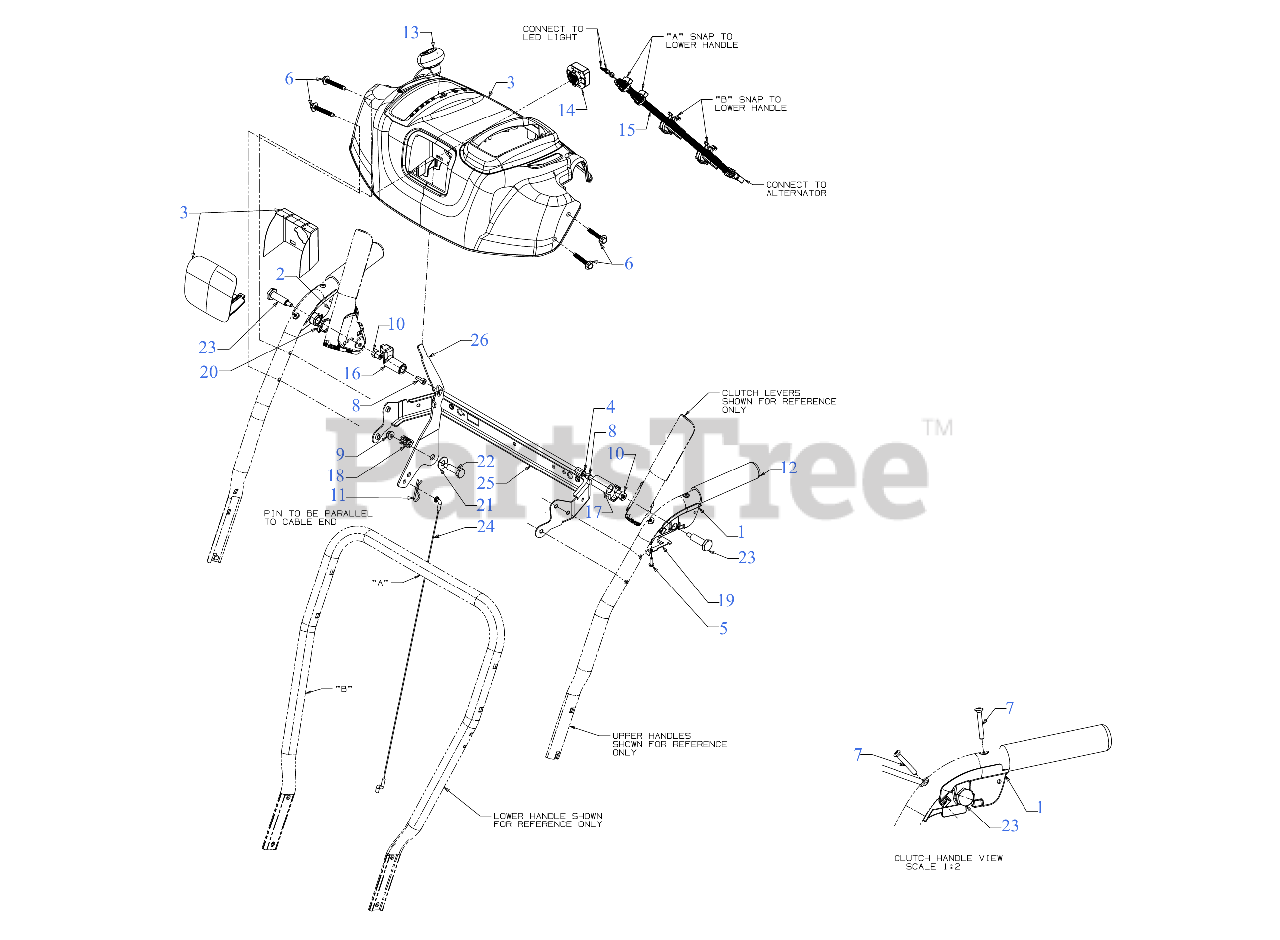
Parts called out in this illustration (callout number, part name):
1	CLUTCH LOCK HANDLE ASSEMBLY (LH)
2	CLUTCH LOCK HANDLE ASSEMBLY (RH)
3	HANDLE PANEL ASSEMBLY
4	PIVOT ROD
5	SCREW #8-16 x .50
6	SCREW 1/4-20 x 1.625
7	SCREW #10-24 x 1.375
8	SCREW 1/4-20 x .50
9	FLANGE LOCK NUT
10	HEX NUT W/PATCH
11	INTERNAL COTTER PIN
13	SHIFT KNOB
14	LED HEADLIGHT SOCKET (150 LUMNES)
15	LIGHT HARNESS
16	LOCK PLATE
17	CLUTCH LOCK CAM
18	COMPRESSION SPRING
19	CLUTCH SPRING
20	TORSION SPRING
21	FLAT WASHER .40X.88X.060
22	SHOULDER SCREW
23	SHOULDER SCREW .437 x 1.345 1/4-20
24	SPEED SELECTOR CABLE (PLASTIC)
25	HANDLE SUPPORT BRACKET (POWDER BLACK)
26	SHIFT LEVER
